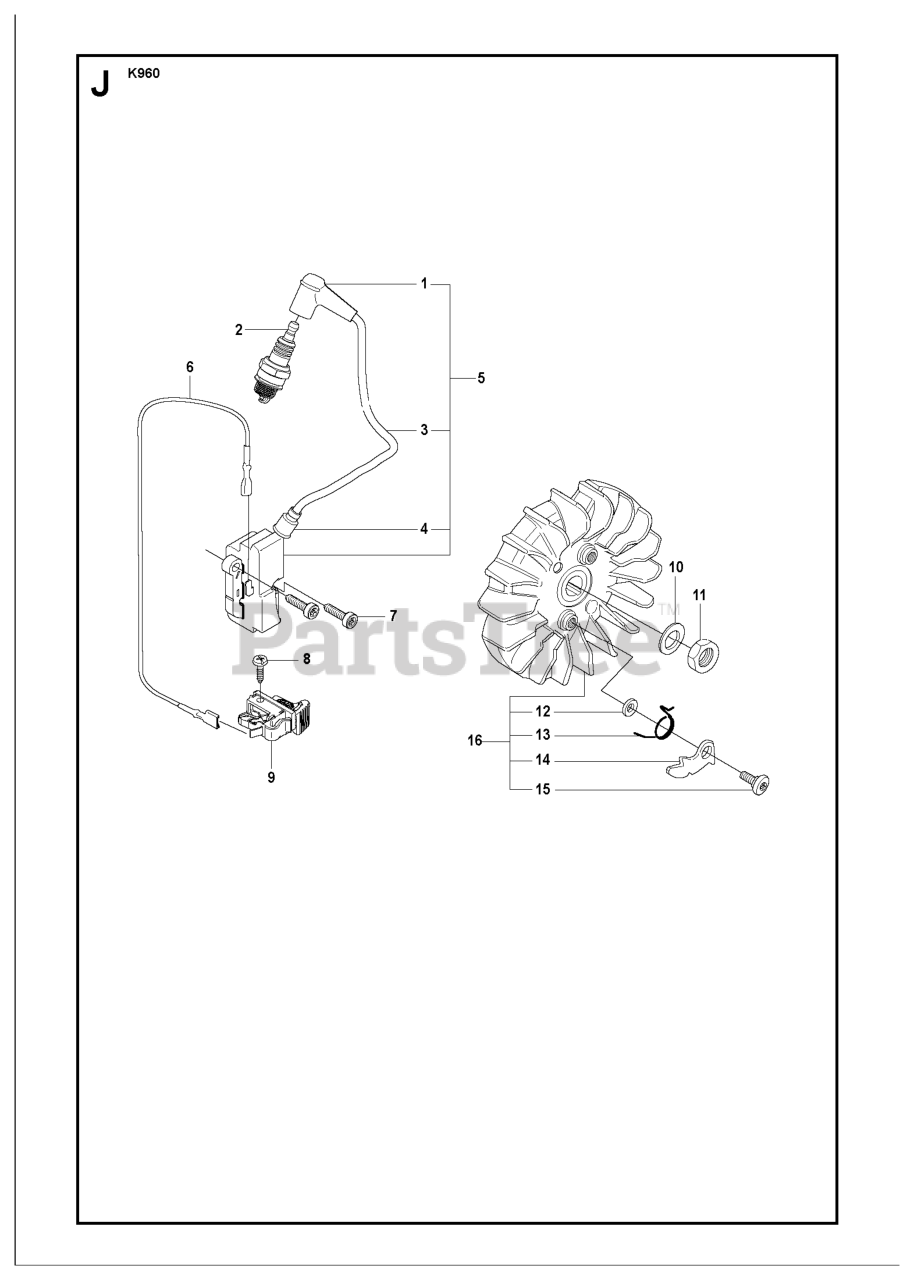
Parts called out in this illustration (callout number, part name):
1	SPARK PLUG CONN. KIT
2	SPARK PLUG RCJ6Y NLA
3	CABLE STOP SWITCH
4	INSULATING CAP
5	IGNITION MODULE
6	SHORTING LEAD
9	STOP SWITCH
10	WASHER 8.4X16
15	SCREW
